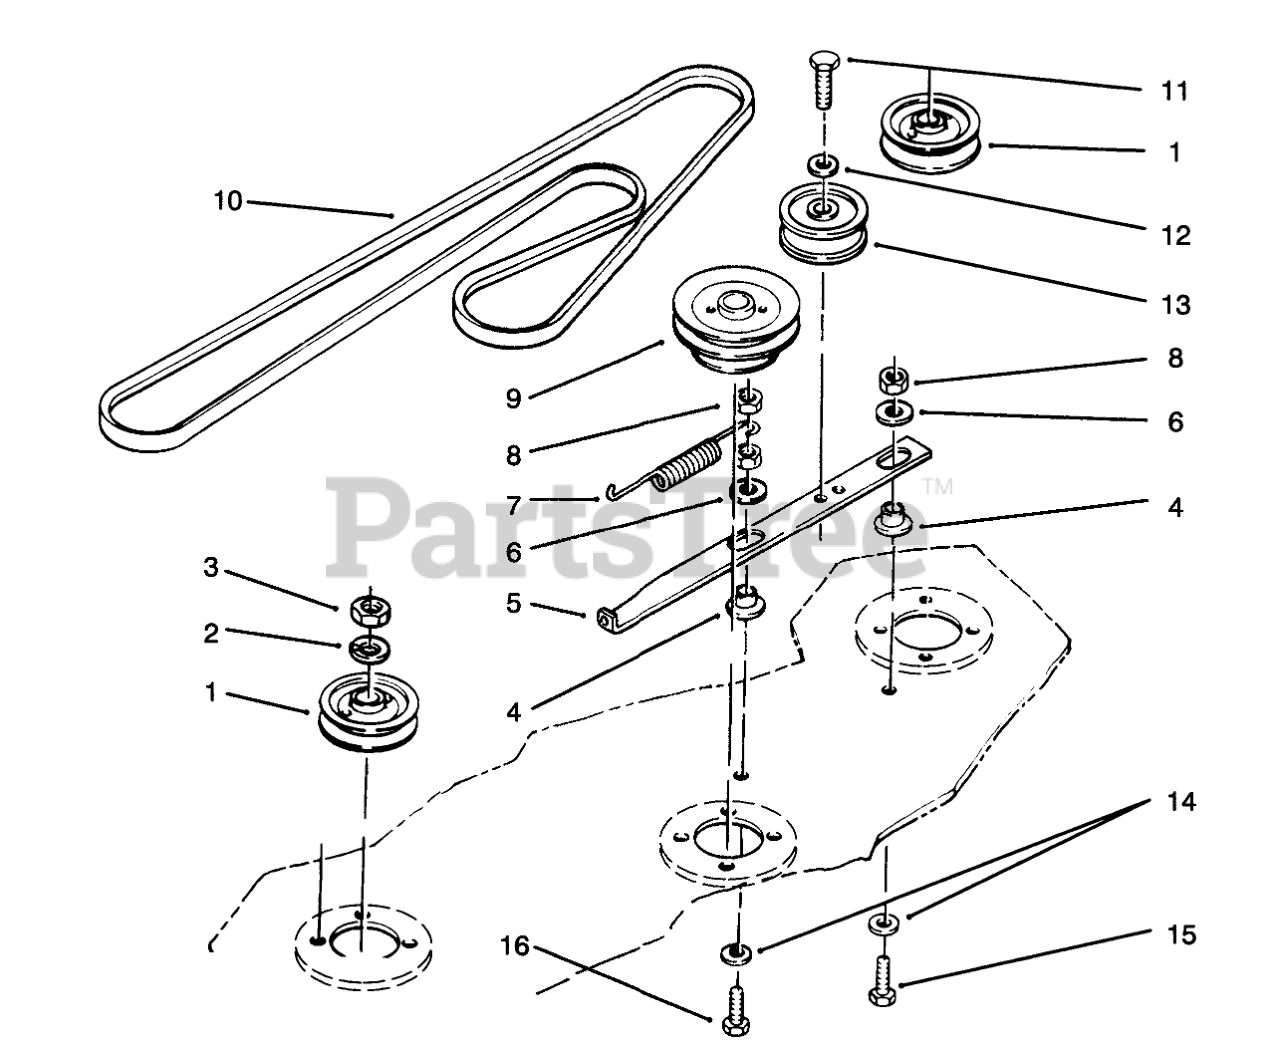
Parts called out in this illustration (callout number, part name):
1	PULLEY
2	WASHER-LOCK
3	NUT-JAM
4	SPACER-BUSHING
5	BAR-IDLER SUPPORT
6	WASHER
7	SPRING-EXTENSION
8	NUT-LOCK, NI
9	PULLEY
10	V-BELT
11	SCREW-HH
12	WASHER-LOCK
13	Idler Pulley
14	WASHER
15	SCREW-HH
16	SCREW-HH
